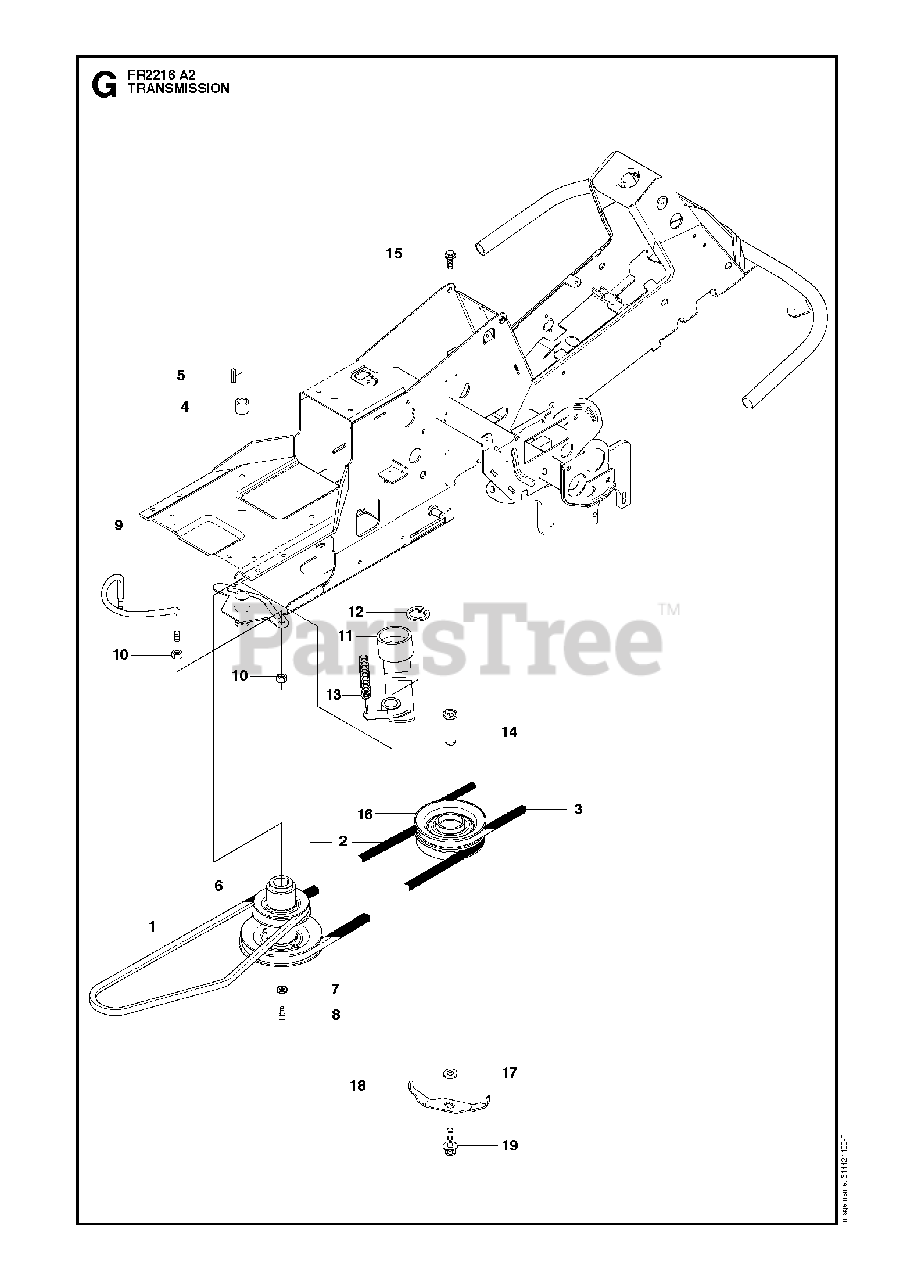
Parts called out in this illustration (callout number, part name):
2	BELT
3	BELT
9	BELT GUIDE
11	TENSIONER
12	RETAINING RING SGA 25
14	SHAFT
18	BELT GUIDE
19	BOLT
